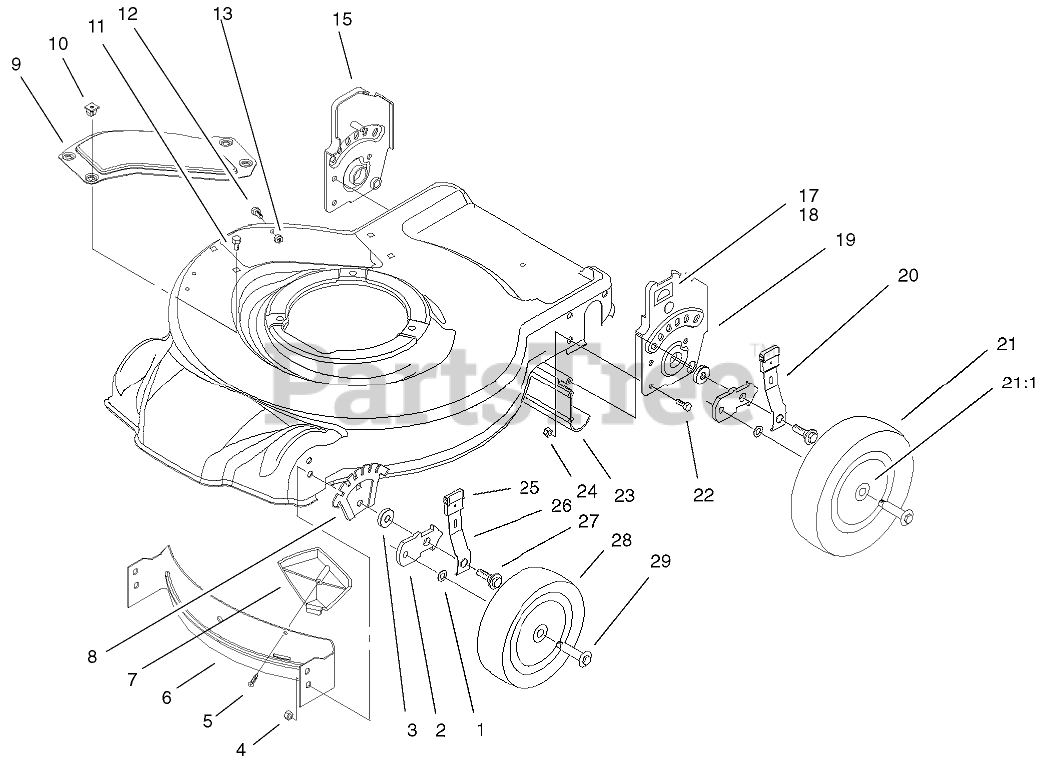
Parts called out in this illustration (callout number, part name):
1	WASHER
2	BRACKET-HEIGHT ADJUSTMENT, WHEEL
3	WASHER
4	NUT-LOCK, NI
5	SCREW-PPH
6	BAFFLE - FRONT
7	KICKER-FRONT
8	PLATE-HEIGHT, ADJUSTMENT
9	COVER - RECYCLING
10	NUT - CLIP
11	SCREW-HWH
13	NUT-LOCK, NI
15	ASM - RH HANDLE BRACKET
17	DECAL-HOC, RH
18	DECAL-HOC, LH
19	ASM - LH HANDLE BRACKET
20	REAR SPRING ARM ASM
21	WHEEL ASM
21:1	BUSHING
22	SCREW-HH
23	SHIELD-TRAILING
24	NUT-LOCK, NI
25	KNOB-LEVER, HEIGHT ADJUSTMENT
26	ARM-FRONT SPRING
27	BOLT-SHOULDER
28	WHEEL ASM
29	BOLT-SHOULDER
